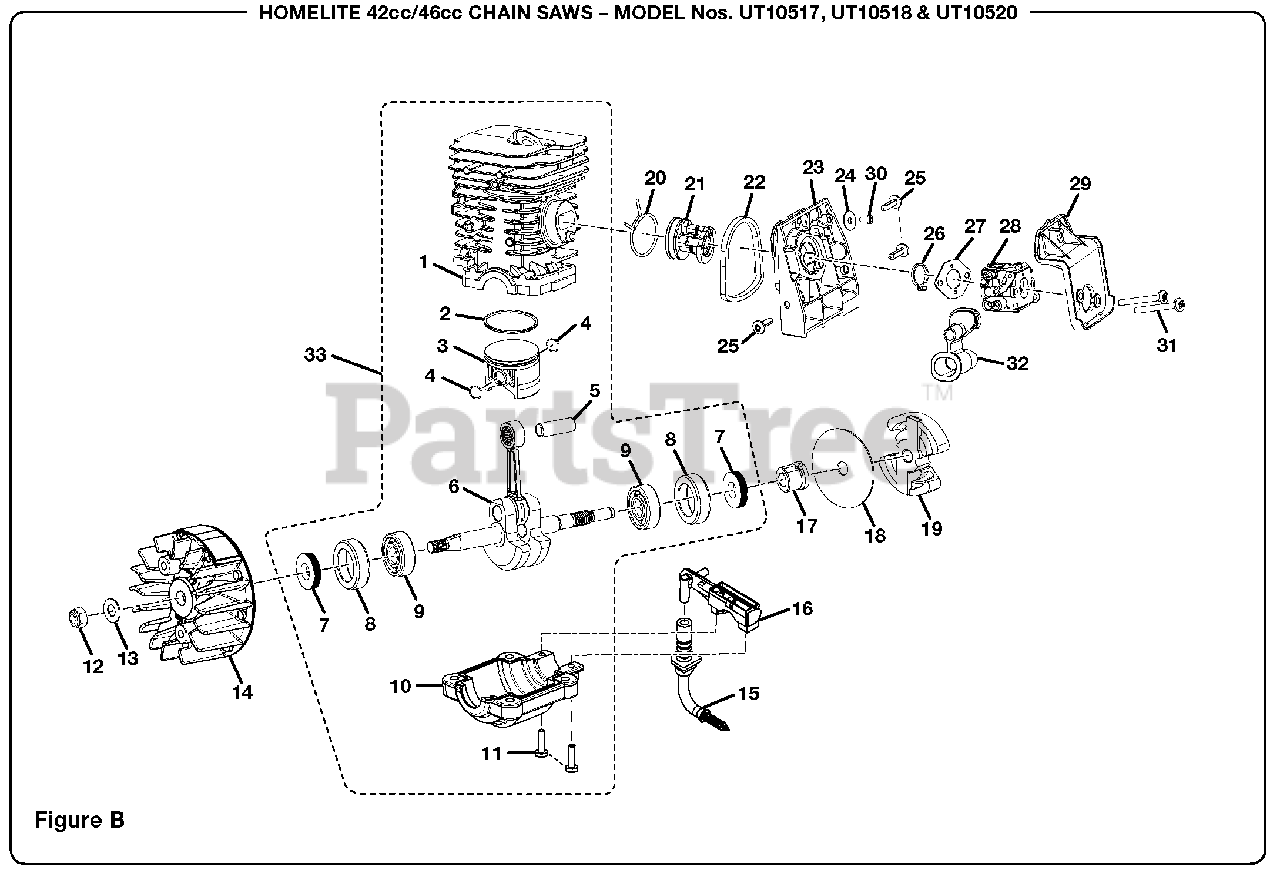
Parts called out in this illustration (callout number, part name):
2	Piston Ring
4	Retaining Ring
5	Piston Pin
6	Crankshaft Assembly
7	Shaft Seal
8	Bearing Case
9	Ball Bearing
10	Crankcase
11	Screw (8-32 x 5/8 in.)
12	Nut (5/14-24)
13	Flat Washer
14	Flywheel Assembly
15	Oil Intake Tube Assembly
16	Oil Pump Assembly
17	Left Hand Worm
18	Thrust Washer
19	Clutch Assembly
20	Wire Clamp
21	Intake Boot
22	Carburetor Adaptor Seal
23	Carburetor Adapter
24	Flat Washer
25	Screw (10-14 x 3/4 in.)
26	Carburetor Plate
27	Carburetor Gasket
28	Carburetor Assembly
29	Air Filter Base
30	Screw (8-16 x 5/16 in.)
31	Screw (10-32 x 1 3/4 in.)
32	Grommet
33	Short Block Assembly (Inc. Key Nos. 1-11)
